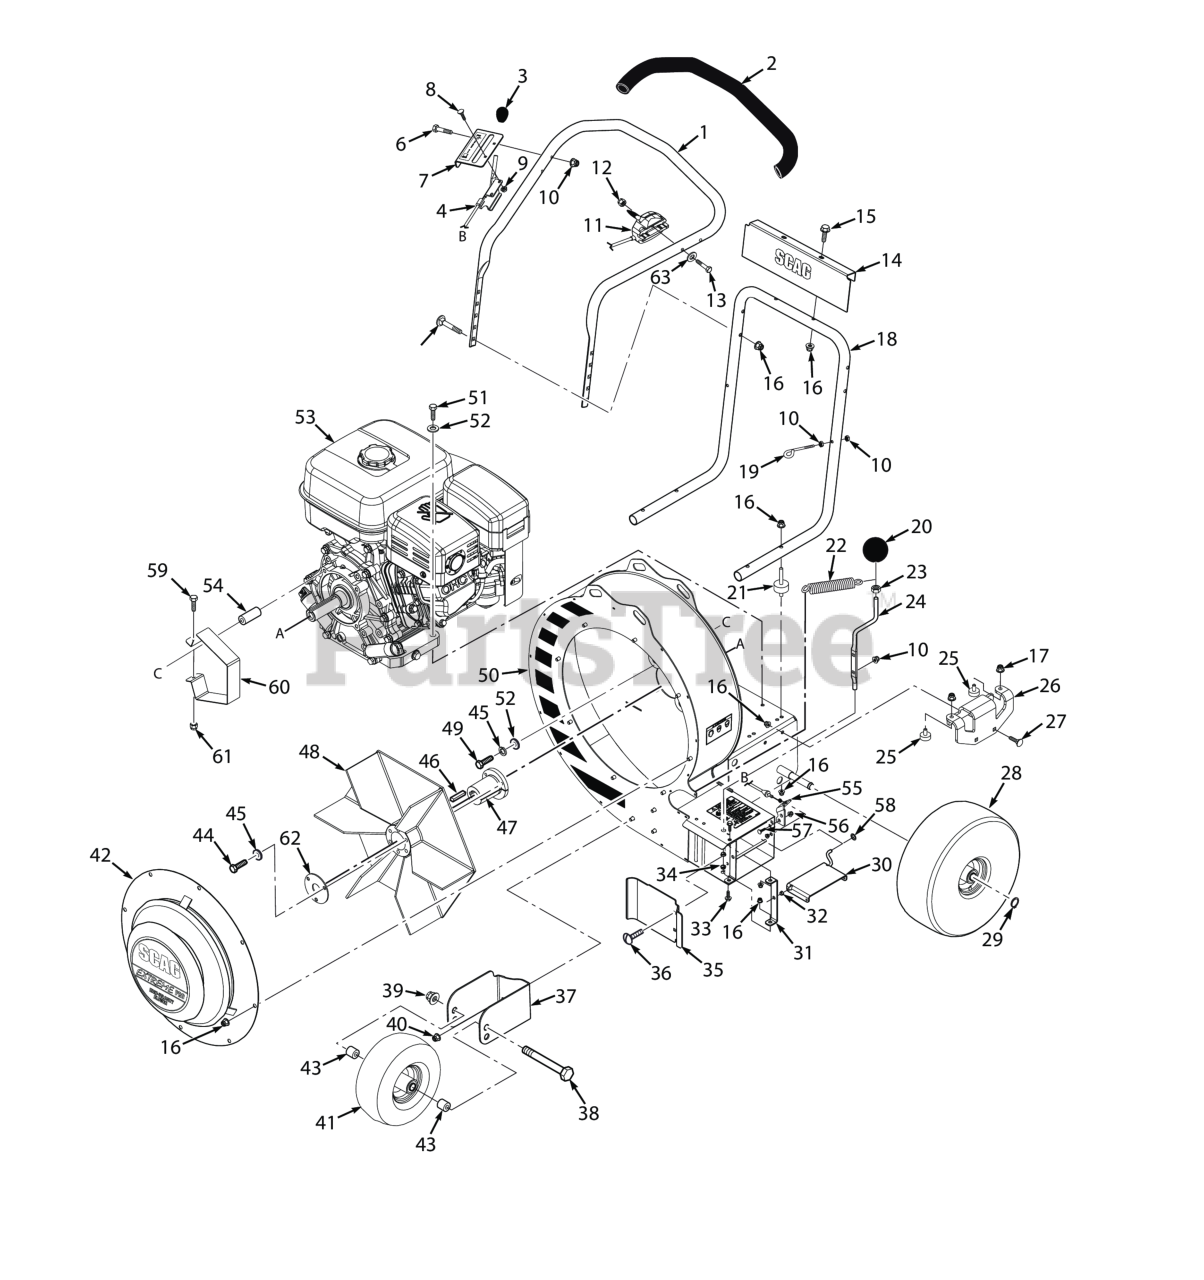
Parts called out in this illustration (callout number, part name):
1	Handle, Upper w/Grip (incl. #2)
2	Grip, 1" x 21-1/2"
3	Knob, Throttle
4	Control Cable, Air Direction (incl. #3)
5	CARR BOLT, 5/16-18 X 1.75
6	Bolt, Hex Head, 1/4-20 x 1-1/2"
7	Mounting Bracket, Control Plate w/Decal
8	Bolt, Carriage #10-24 x 1/2"
9	Nut, Elastic Stop #10-24
10	NUT, 1/4-20 SERRATED FLANGE HEX HEAD
11	Cable, Throttle Control
12	HEX, NUT, ELASTIC STOP LOCK, 1/4-20
13	Bolt, 1/4-20 x 2-1/2"
14	Handle Bar Cover w/Decal
15	Bolt, Serrated Flange Hex Head 5/16-18 x 1.50"
16	Nut, Flange Head Elastic Stop 5/16-18
17	Nut, Serrated Flange 5/16-18 (Right Front Engine Mounting, Briggs and Kohler Only)
18	Handle, Lower - LBX
19	Guide, Pull Rope
20	Knob, 3/8-16 Thread
21	Mount, Vibration
22	Spring, Air Discharge Door
23	HEX LOCKNUT, ELASTIC STOP, 3/8-16
24	Rod, Forward Air Control
25	Bumper, Rubber 5/16-18 x 5/8"
26	Bracket, Limiter Plate
27	CARR BOLT, 5/16-18 X 1.75
28	Wheel Assembly, 13 x 5-6
28	Rim w/Valve
28	Bearing
29	RETAINING RING, 5/8 EXT. - BASIC
30	Door Weldment, Side Discharge Control
31	Pivot Bracket, Side Discharge
32	Bearing, .250 ID
33	Capscrew, 5/16-18 x .75 Serrated Flange Hex Head
34	Bearing, .375 ID
35	Door, Forward Air Control
36	Bolt, Carriage 1/4-20 x 1/2"
37	Caster Bracket, Extreme
38	BOLT, HEX HEAD, 5/8-11 X 5-1/2
39	HEX LOCKNUT, ELASTIC STOP, 5/8-11
40	Nut, Flange Elastic Stop Nut, 3/8-16
41	Wheel Assembly, 4.10 x 3.5-6
41	Rim w/Valve
41	Bearing
42	Baffle Assembly, Extreme Pro w/Decal
43	Spacer, Wheel
44	Bolt, Hex Head 5/16-18 x 3-3/4" Grade 8
45	Lockwasher, 5/16 (.317 x .586 x .078) Helical Spring
46	Key, 1/4 x 1/4 x 2.0"
47	Tapered Hub, P2 - 1" Bore
48	Impeller Weldment, 17" Extreme Pro
49	Bolt, Hex Head 5/16-24 x 2-1/2"
50	Housing Weldment, Extreme Pro with Decals
51	Bolt, Hex Head 5/16-18 x 1-1/2" - Front
52	Flatwasher, 5/16-.375 x .875 x .083 (35BV & 37BV-EFI)
53	Engine, Honda GX390 (not available through Scag Power Equipment)
54	Spacer, Engine
55	Bracket, Air Flow
56	Nut, Flanged Elastic Stop 1/4-20
57	Serr. Fl. Hex Head CPSCR, 1/4-20 x 3/4"
58	NUT, PUSH-ON - .1/4 SHAFT
59	Capscrew, Hex Head 1/4-20 x 1"
60	Guard, Impeller - LBXP
61	HEX, NUT, ELASTIC STOP LOCK, 1/4-20
63	Flatwasher, 1/4 (.281 x .625 x .065)
